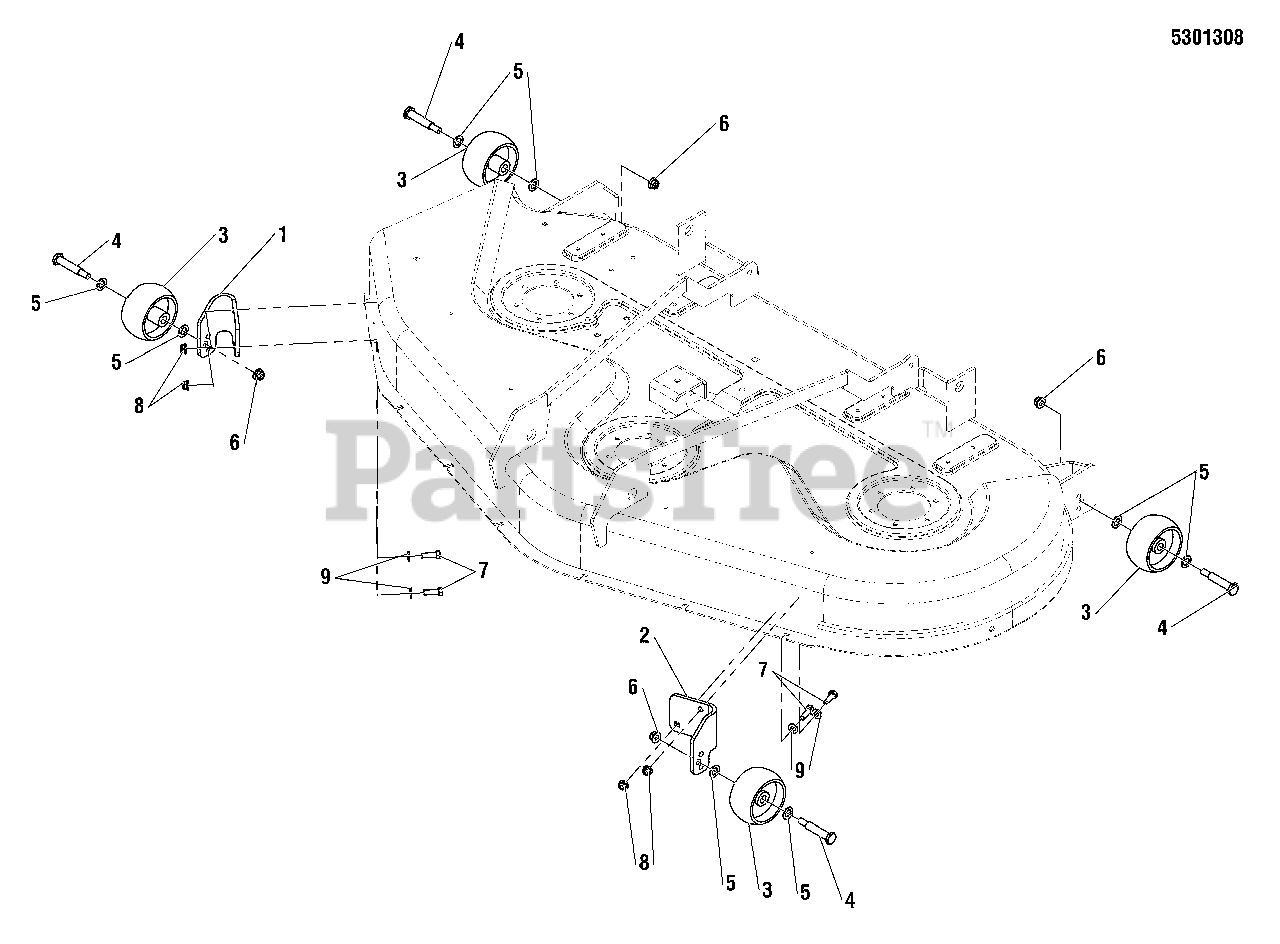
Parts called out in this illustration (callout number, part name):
1	BRACKET, GAUGE WHEEL, RH - RED
2	BRACKET, GAUGE WHEEL, LH - RED
3	WHEEL- 2.00 WIDE 3.92 DIA 0.531ID POLY
4	BOLT - WHEEL 3/8-16X2.781 .750 THRD YELLOW
5	WASHER, 0500(0.51IDX0.87ODX.06THK) BLK
6	NUT, 3/8-16 HEX NYLOCK FLANGE
7	BOLT, 5/16-18 X 1 GD5 YZ
8	NUT, 5/16-18 HEX NYLOCK FLANGE
9	WASHER, 5/16" SAE
